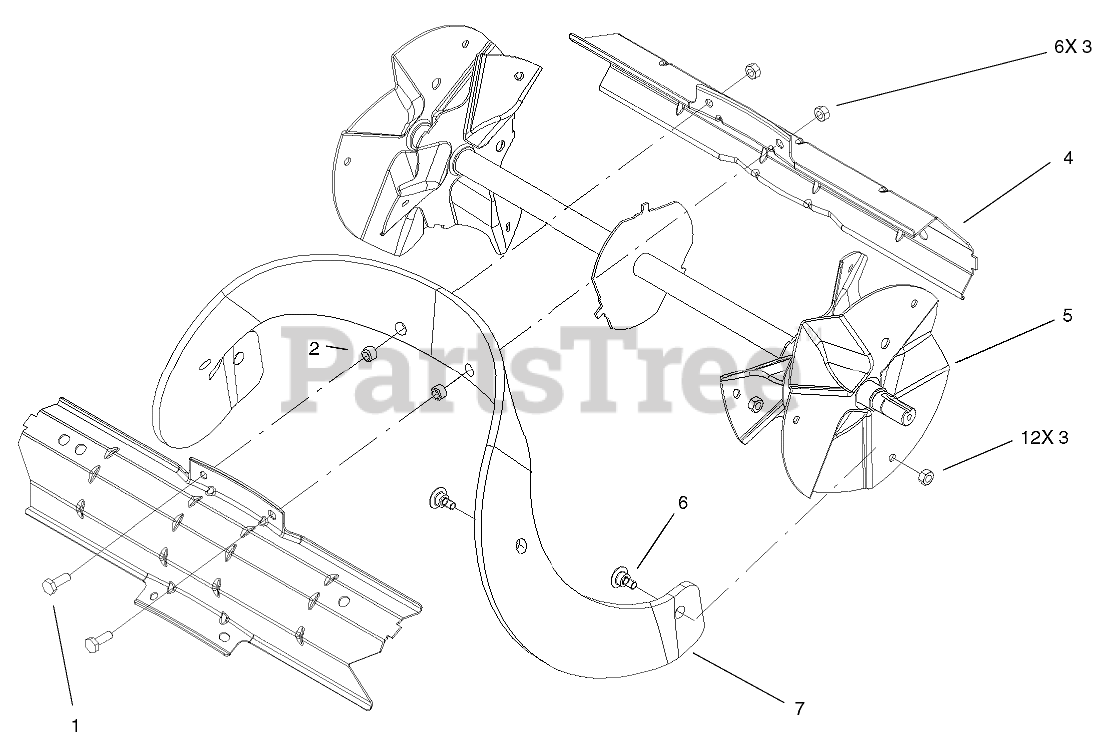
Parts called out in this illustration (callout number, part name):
1	SCREW-HH
2	SPACER-BLADE, ROTOR
3	NUT-LOCK, NI
4	DRUM-ROTOR
5	ROTOR ASM
6	SCREW
7	BLADE-ROTOR
